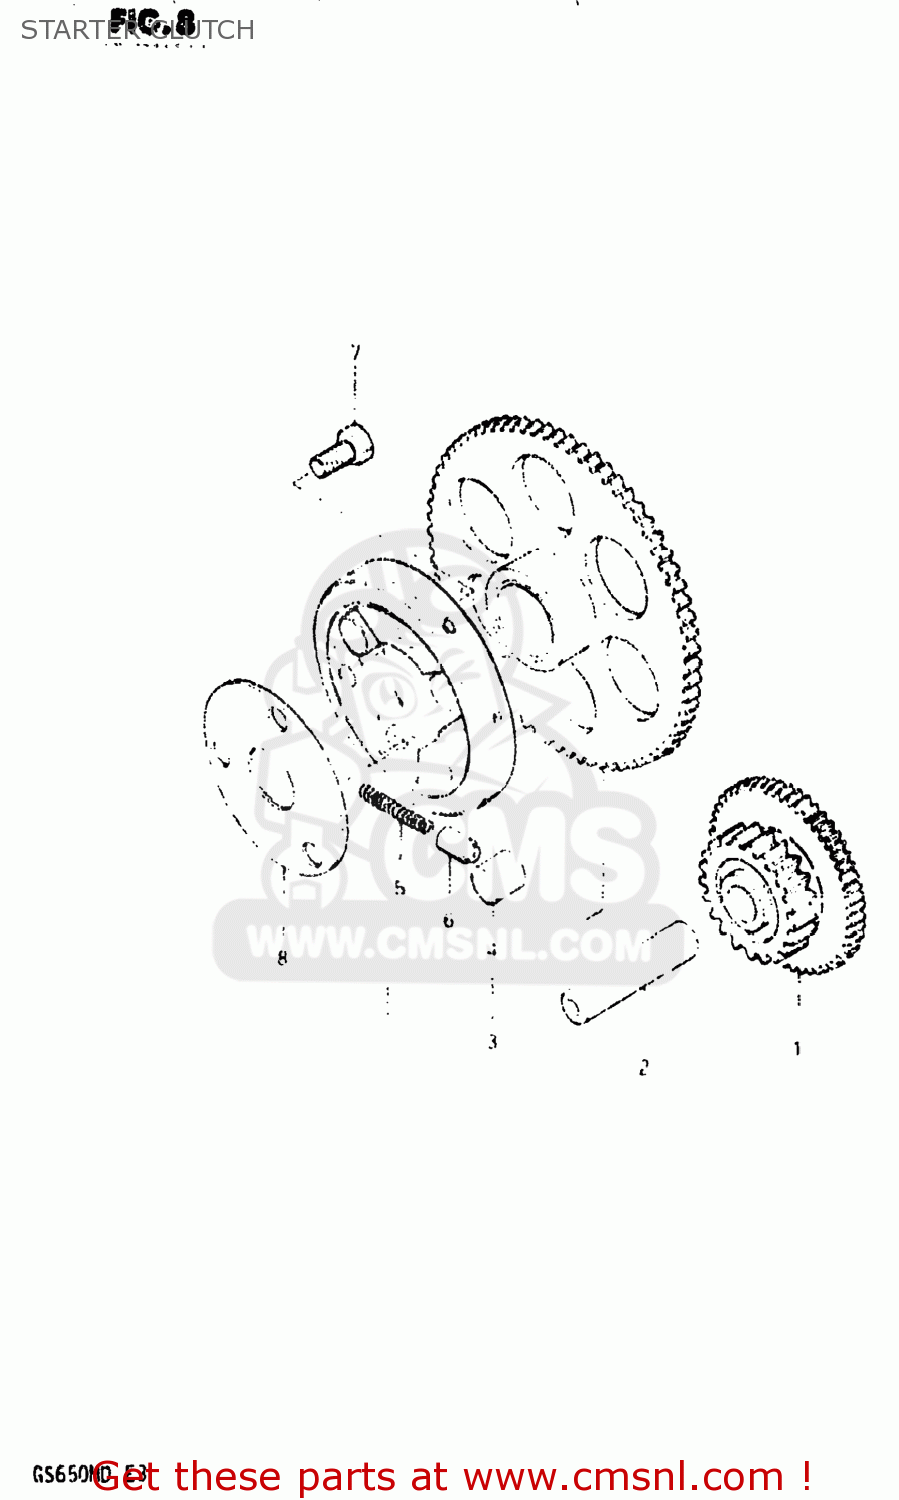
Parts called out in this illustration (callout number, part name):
1	GEAR,STARTER IDLE
2	PIN(7.4X13X56)
3	CLUTCH SET,STARTER
4	ROLLER(15X13)
5	SPRING
6	PIECE,PUSH
7	BOLT
8	SHIM,STARTER CLUTCH HUB
